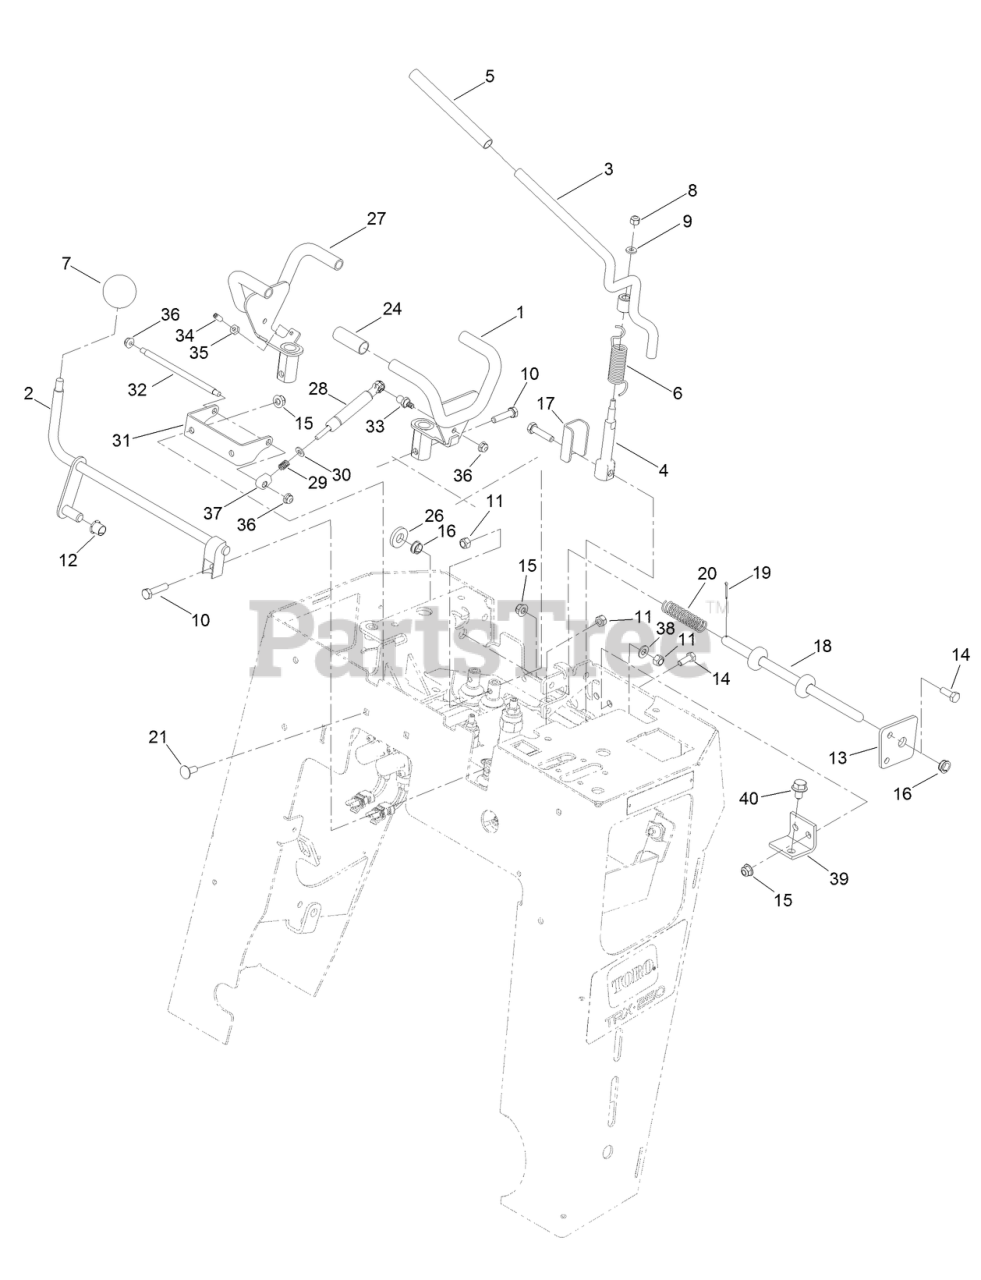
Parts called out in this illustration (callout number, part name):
1	HANDLE-TRACTION, LH
2	LEVER-LIFT
3	AUXILIARY LEVER ASM
4	LEVER-DRIVE, CHAIN
6	SPRING-TORSION
8	NUT-LOCK, NI
9	WASHER-FLAT
10	SCREW-HH
11	NUT-LOCK, NI
12	BUSHING-NYLINER
13	PLATE-BUSHING
14	SCREW-HH
15	NUT-HF, NI
16	BUSHING
17	BRACKET-LEVER
18	ROD-LOCKOUT
19	PIN-COTTER
20	SPRING-COMPRESSION
21	SCREW-CARR
26	WASHER-HARDENED
27	HANDLE-TRACTION, RH
28	DAMPER
29	SPRING-COMPRESSION
30	WASHER-SPCL
31	BRACKET-DAMPER
32	ROD-DAMPER
33	STUD-BALL
34	SCREW-SET, HS
35	NUT-JAM
36	NUT-HF
37	FITTING-CLEVIS
38	WASHER-PLAIN
39	BRACKET-VALVE
40	SCREW-HHF
